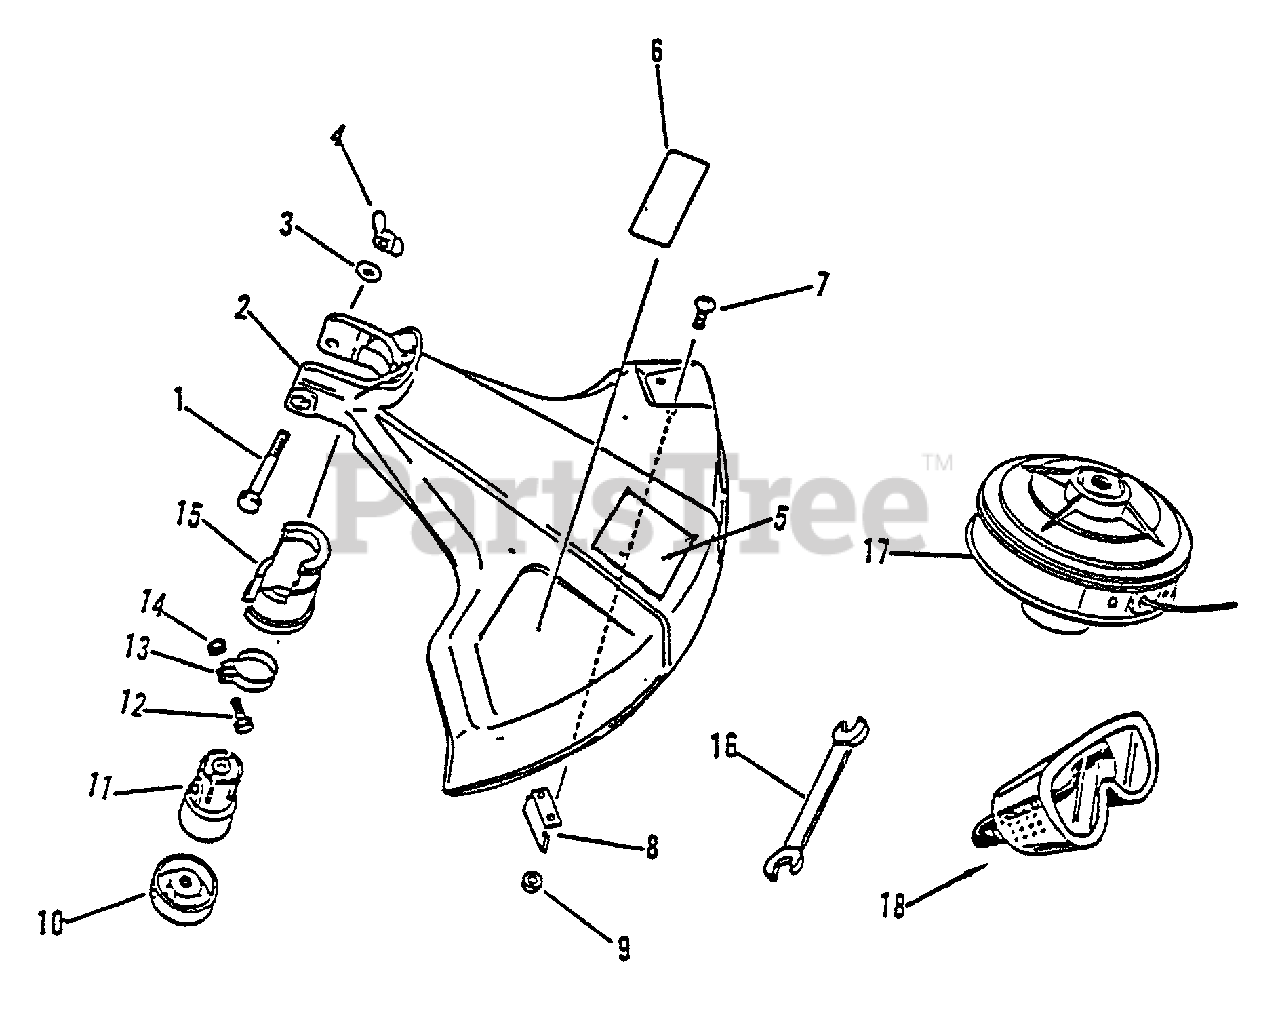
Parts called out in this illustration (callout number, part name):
1	BOLT - 6×50
2	SHIELD
3	WASHER 6.5×11.5×0.8
4	NUT, WING 6
5	LABEL, CAUTION
6	LABEL, ECHO
7	SCREW 5×16
8	KNIFE, TRIMMER LINE
9	NUT M5
10	PLATE, ADAPTER - UPPER
11	GEAR CASE ASSY
14	NUT M5
15	BRACKET, BEARING CASE
16	SPANNER 8×10
17	GT ECHOMATIC® HEAD
18	GOGGLES
